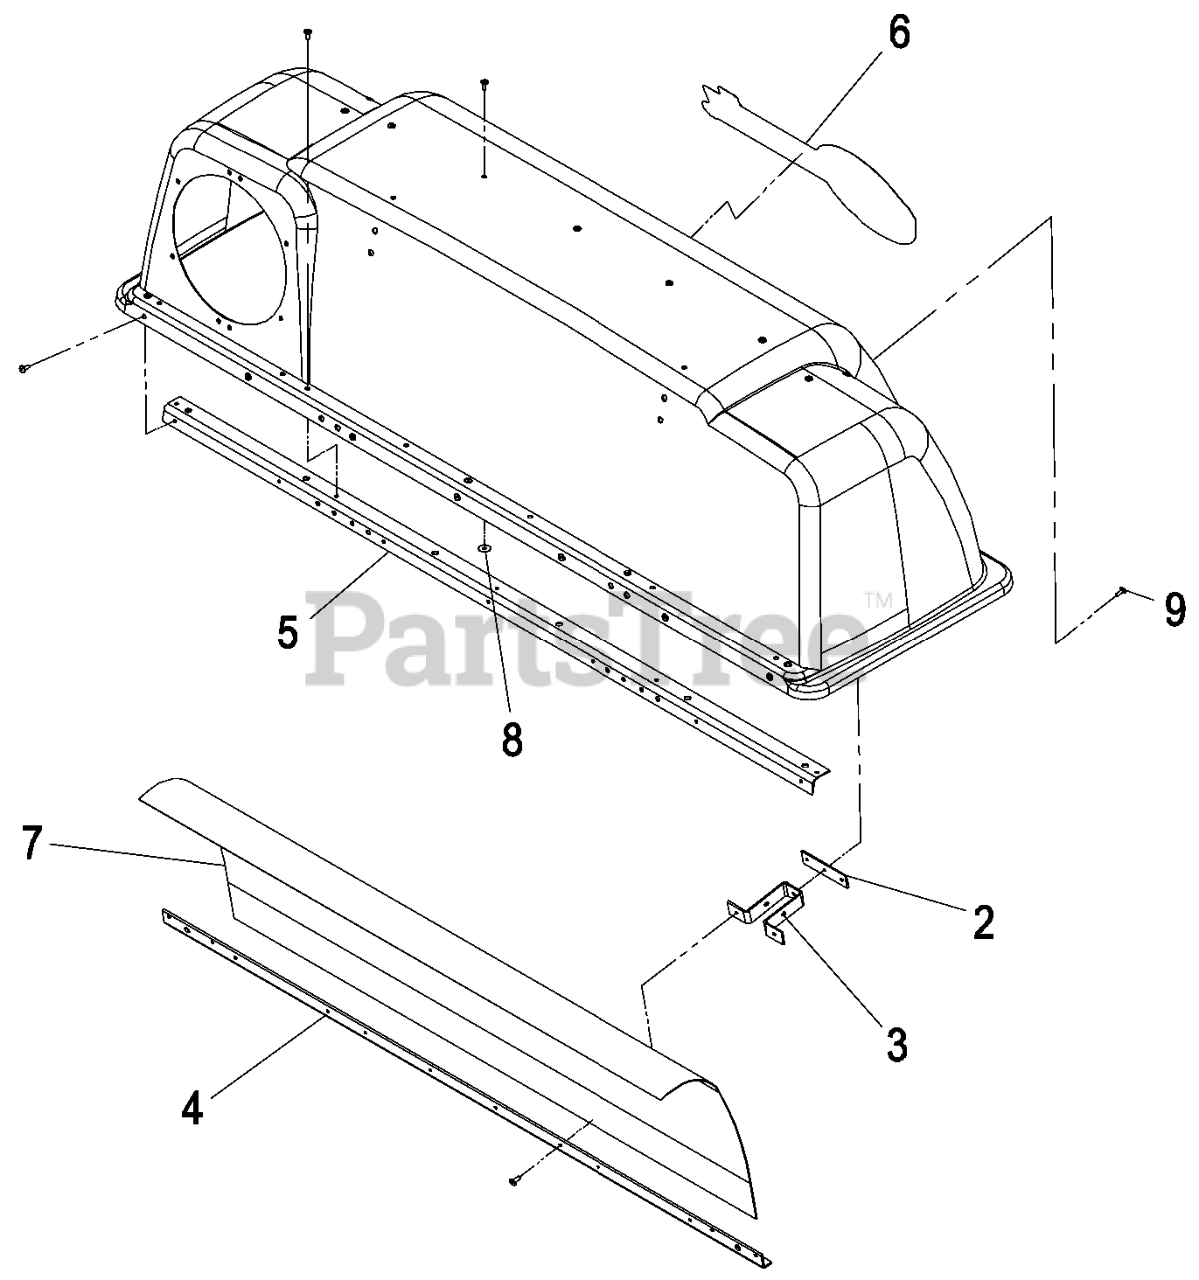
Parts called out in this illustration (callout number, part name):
2	PLATE-LATCH, REINFORCEMEN
3	BRACKET-MOUNT
4	SUPPORT-SCREEN
5	STIFFENER-BAGGER, TOP
6	DECAL, EXMARK
7	SCREEN-BAGGER
8	WASHER-FLAT
9	RIVET-BLIND
